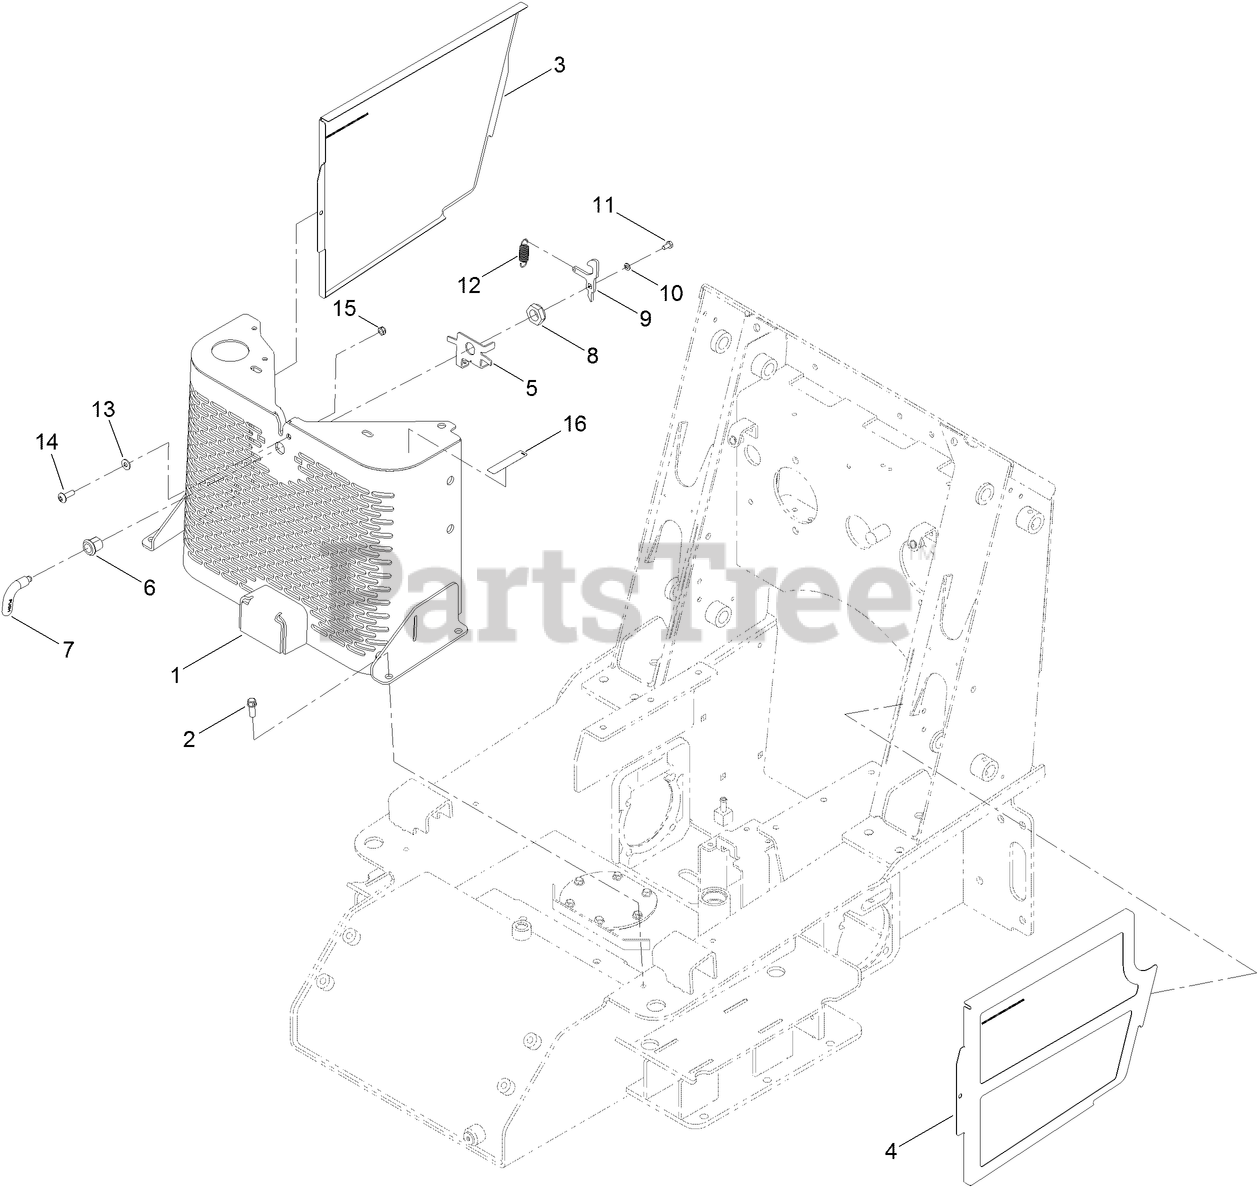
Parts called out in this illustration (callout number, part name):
2	SCREW-TAPTITE
3	RH SIDE PANEL
4	LH SIDE PANEL
5	BRACKET-LATCH
6	HOUSING-LATCH
7	HANDLE-LATCH
9	CAM-LATCH
10	SCREW-HH
11	SCREW-HH
12	SPRING
13	WASHER-FLAT
14	SCREW-PTH
15	NUT-LOCK, NI
16	DECAL-WARNING, FAN
